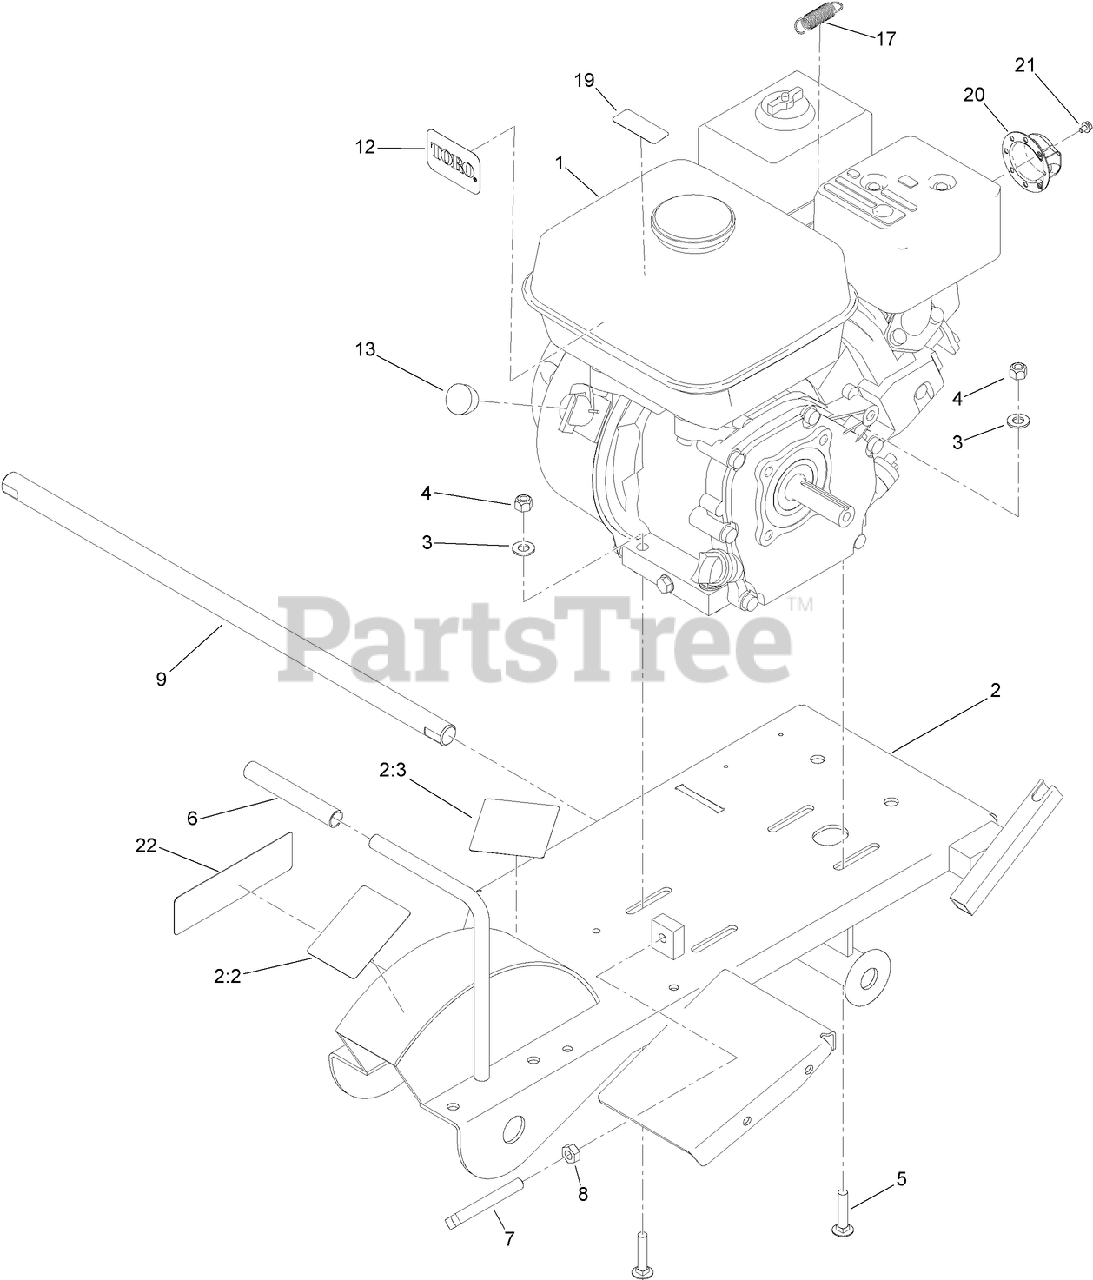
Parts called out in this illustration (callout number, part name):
2	FRAME ASM
2:2	DECAL-CAUTION
2:3	DECAL-DANGER
3	WASHER-FLAT
4	NUT-LOCK, NI
5	BOLT-CARR
6	GRIP-RUBBER
7	SCREW-SET, SQH
8	NUT-HEX
9	BAR-AXLE, WHEEL
12	Decal
13	PLUG-ENGINE
17	SPRING-EXTENSION
19	DECAL-WARNING, ETHANOL
20	DEFLECTOR
21	SCREW-HWH
22	DECAL-ROTATE TOOTH
